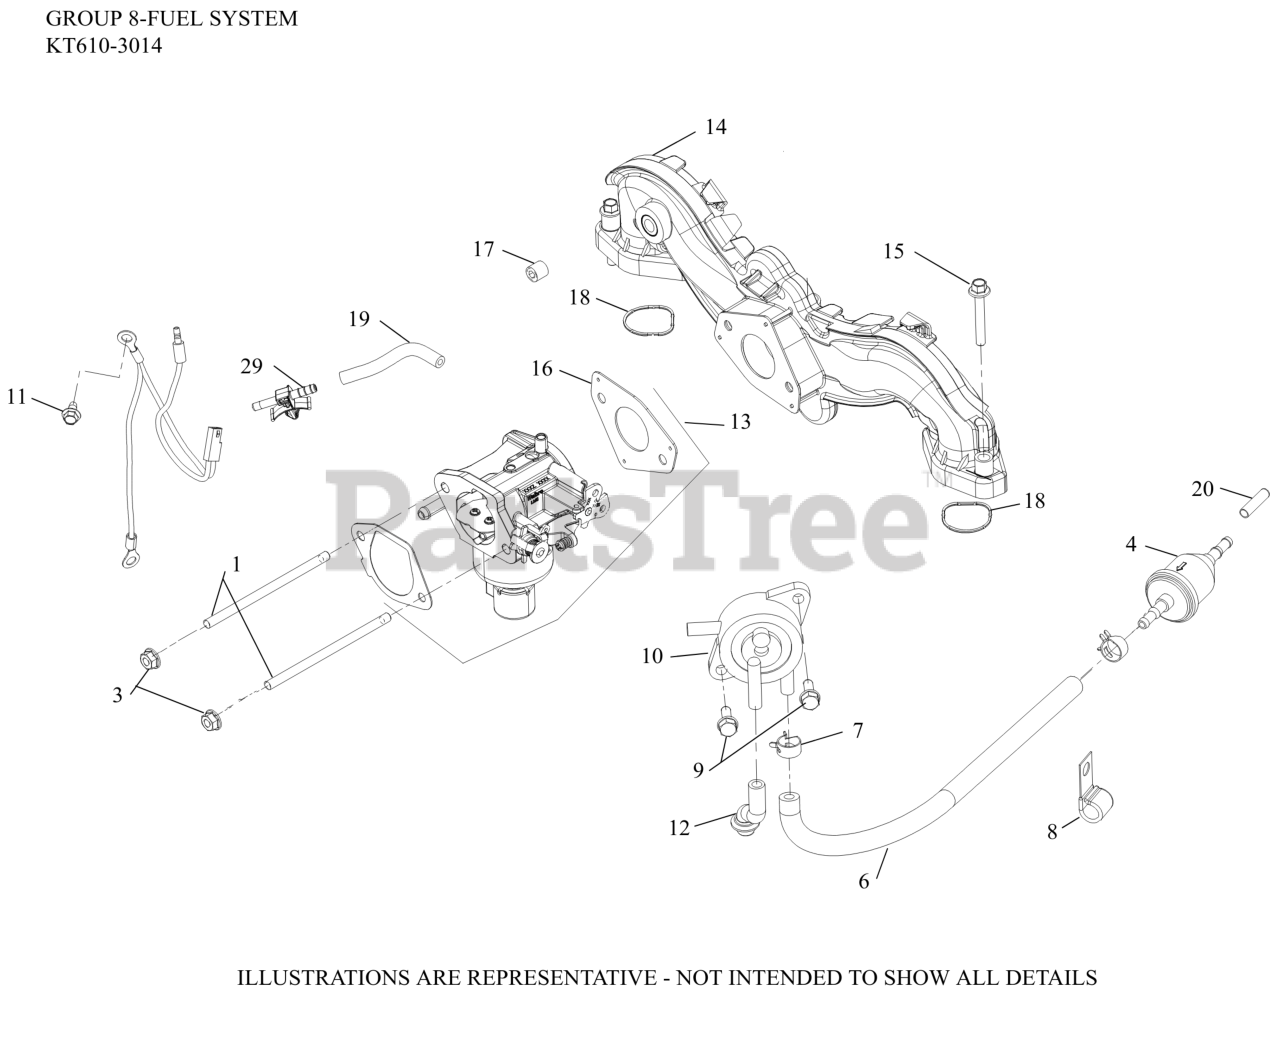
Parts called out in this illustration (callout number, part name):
3	NUT, FLG M6X1.0
4	FILTER,FUEL 51 MICRON (FUEL PUMP)
6	HOSE,LW PERM.FUEL 24.00"-USE 25 111 81-S
7	SPRING CLAMP, HOSE
8	CLIP, CABLE
9	SCREW, TAP M6X1.7X18
10	PUMP, FUEL (PULSE)-(#2539326S)
11	SCREW, THREAD FORMING
12	HOSE, PULSE PUMP(STEEL COVERS)
13	KIT,CARB(WALBRO)
14	KIT, INTAKE MANIFOLD-(#24164277S)
15	SCREW, FLG M6X1.0X40
16	GASKET, CARBURETOR
17	PLUG, CTSK PIPE 1/8"
18	O-RING, INTAKE PORT (PIM)
19	HOSE EVAPORATIVE (WALBRO)
20	CAP, MASKING
29	CONNECTOR, EVAPORATIVE
NI	KIT,REPAIR OVERHAUL(WALBRO)
NI	KIT,BOWL O-RING(WALBRO)
NI	KIT, HI ALTITUDE (5000 FT) 19MM
NI	KIT,SOLENOID REPAIR(WALBRO)
NI	KIT,REPAIR FLOAT(WALBRO)
